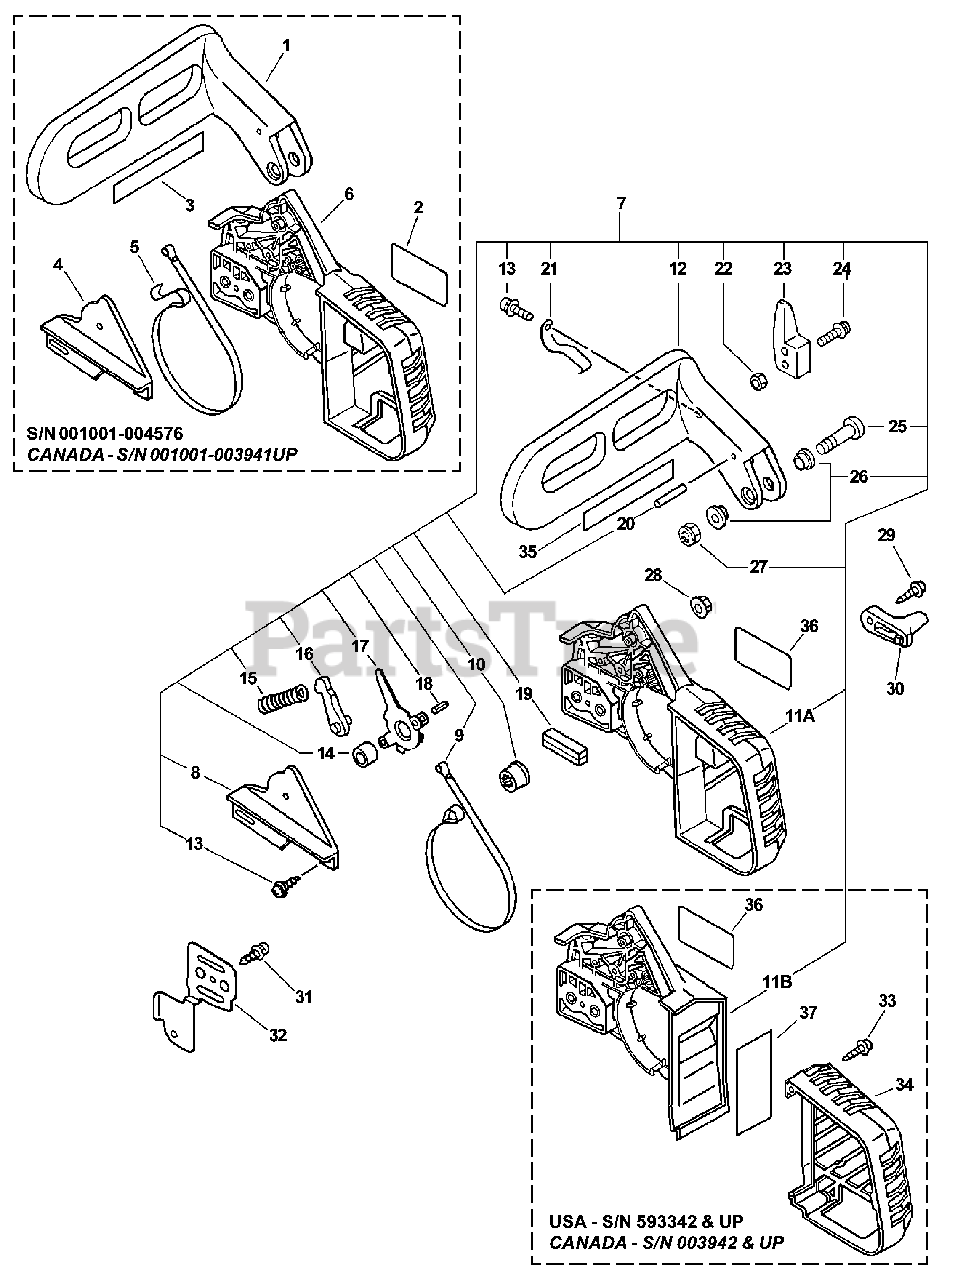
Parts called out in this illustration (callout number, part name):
1	LEVER, BRAKE
2	LABEL - MODEL
3	LABEL, BAR & CHAIN
4	COVER, BRAKE
5	BAND, BRAKE
6	GUARD, SPROCKET
7	CHAIN BRAKE ASSY
8	COVER, BRAKE
9	BAND, BRAKE
10	ADJUSTER, BRAKE
11A	GUARD, SPROCKET
11B	GUARD, SPROCKET
12	LEVER, BRAKE
13	SCREW 4×10
14	SPACER 8×12×9
15	SPRING, COMPRESSION
16	STOPPER, BRAKE
17	LEVER, BRAKE
18	PIN, SPRING 4×8.8
19	SEAL, BRAKE
20	ROLLER 4×23.8
21	SPRING, FLAT
23	WEIGHT, BRAKE
24	SCREW 4×22
25	SCREW 5×32
26	COLLAR 5.3×10×13×L5
27	NUT, LOCK M5
28	NUT, FLANGE M6
29	SCREW, TAPPING 5×20
30	CHAIN CATCHER
31	SCREW 4×10
32	PLATE, GUIDE
33	SCREW, TAPPING 5×20
34	COVER, EXHAUST
35	LABEL, MODEL
36	LABEL, BAR & CHAIN
37	SHIELD, HEAT 35×60×0.10
